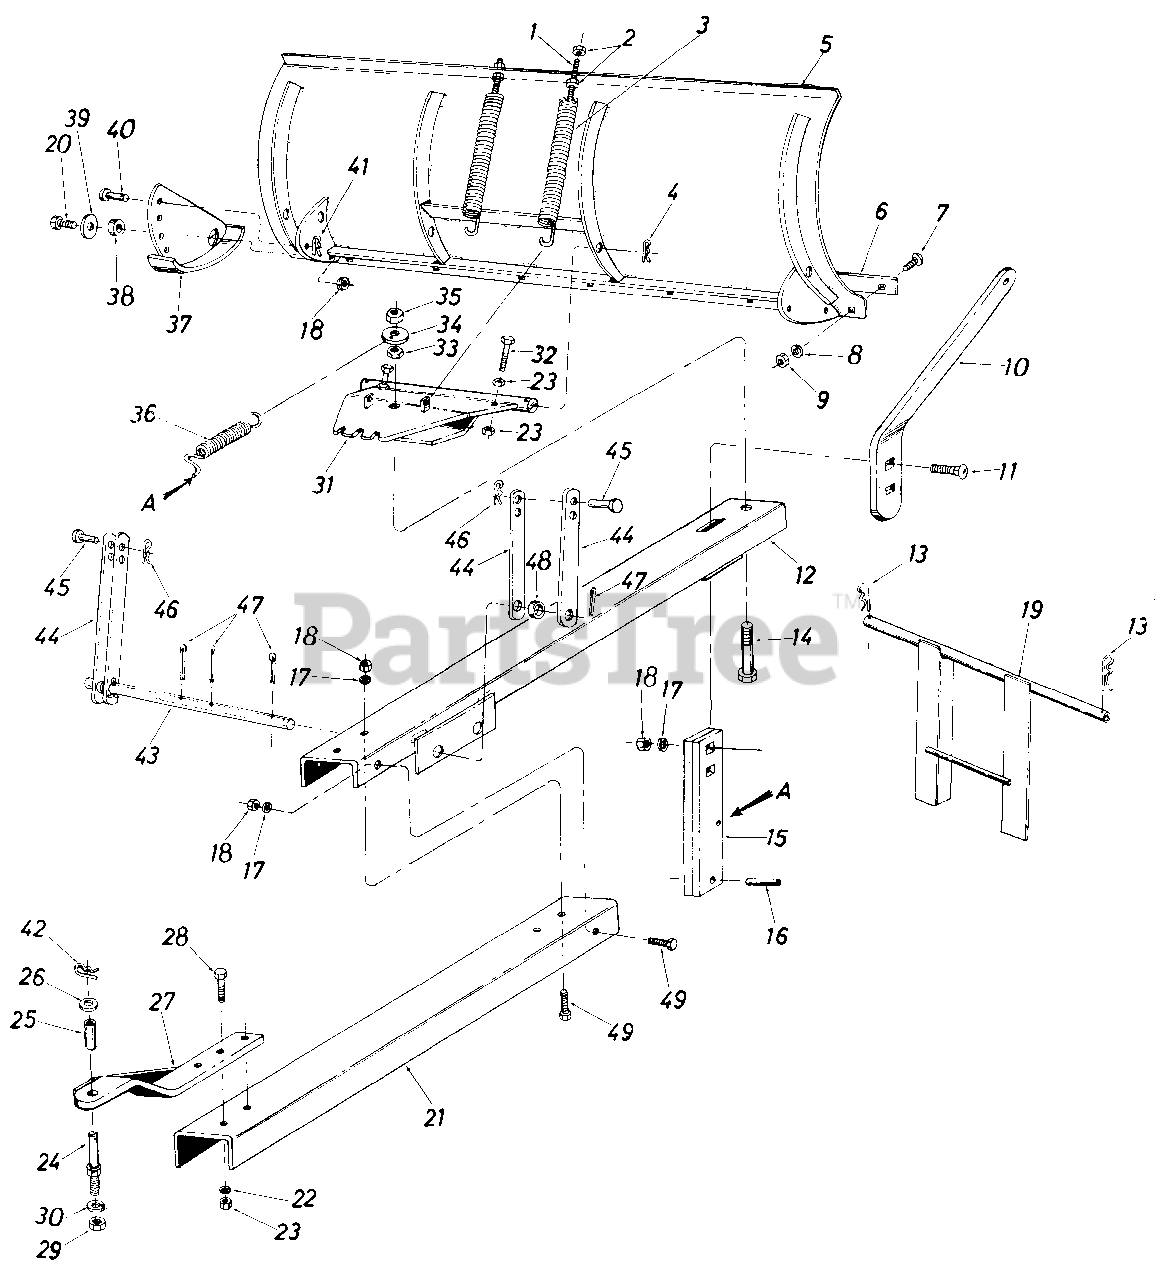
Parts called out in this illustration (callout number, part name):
1	Hex Scr. 3/8-16 x 4.50" Lg.*
2	Hex Nut 3/8-16 Thd.*
3	Blade Adjustment Spring
4	Hair Pin Cotter, 5/32
5	54" Blade Ass'y.
6	Wear Plate
7	Carriage Bolt 5/16-18 x .75" Lg.*
8	L.-Wash. 5/16" Scr.*
9	Hex Nut 5/16-18 Thd.*
10	Lock Extension Bar
11	Carriage Bolt 3/8-16 x 1.25" Lg.*
12	Front Push Bar Ass'y.
13	Hair Pin Cotter, 5/32
14	Hex Scr. 3/4-10 x 3.50" Lg.*
15	Angle-Lock Bar
16	Spring Pin Spirol .25" Dia. x 1.00" Lg.
17	L.-Wash. 3/8" Scr.*
18	Hex L.-Nut 3/8-16 Thd.*
19	Guide Bracket Ass'y.
20	Hex Scr. 3/8-16 x .75" Lg.*
21	Rear Push Bar Channel
22	L.-Wash. 1/2" Scr.*
23	Hex Nut 1/2-13 Thd.*
24	Link Clevis Pin
25	Spacer 1" O.D. x 21/32" I.D. x .75" Lg.
26	Fl-Wash. 21/32 I.D. x .090 O.D.
29	Hex Jam L.-Nut 5/8-18 Thd.
30	L.-Wash. 5/8" Scr.*
31	Pivot Plate Ass'y.
32	Hex Scr. 1/2-13 x 2.00" Lg.*
33	Hex Jam Nut 3/4-10 Thd.
34	Fl.-Wash. 3/8" Special)
35	Hex Lock Nut 3/4-10 Thd.
36	Angle Lock Spring
37	Skid Assembly
38	Bushing, Pivot Skid
39	Fl.-Wash. .385" I.D. x 1.00" O.D.
40	Clevis Pin 5/16" Dia. x 3/4" Lg.
41	Hair Pin Cotter 3/32"
42	Hair Pin Cotter, 5/32
43	Lift Shaft
44	Lift Link
45	Clevis Pin 1/2" Dia. x 1.00" Lg.
46	Hair Pin Cotter, 3/32"
47	Cotter Pin 1/8" Dia. x 1.50" Lg.*
48	Spacer, Lift Link
49	Hex Scr. 3/8-16 x 1.00" Lg.*
